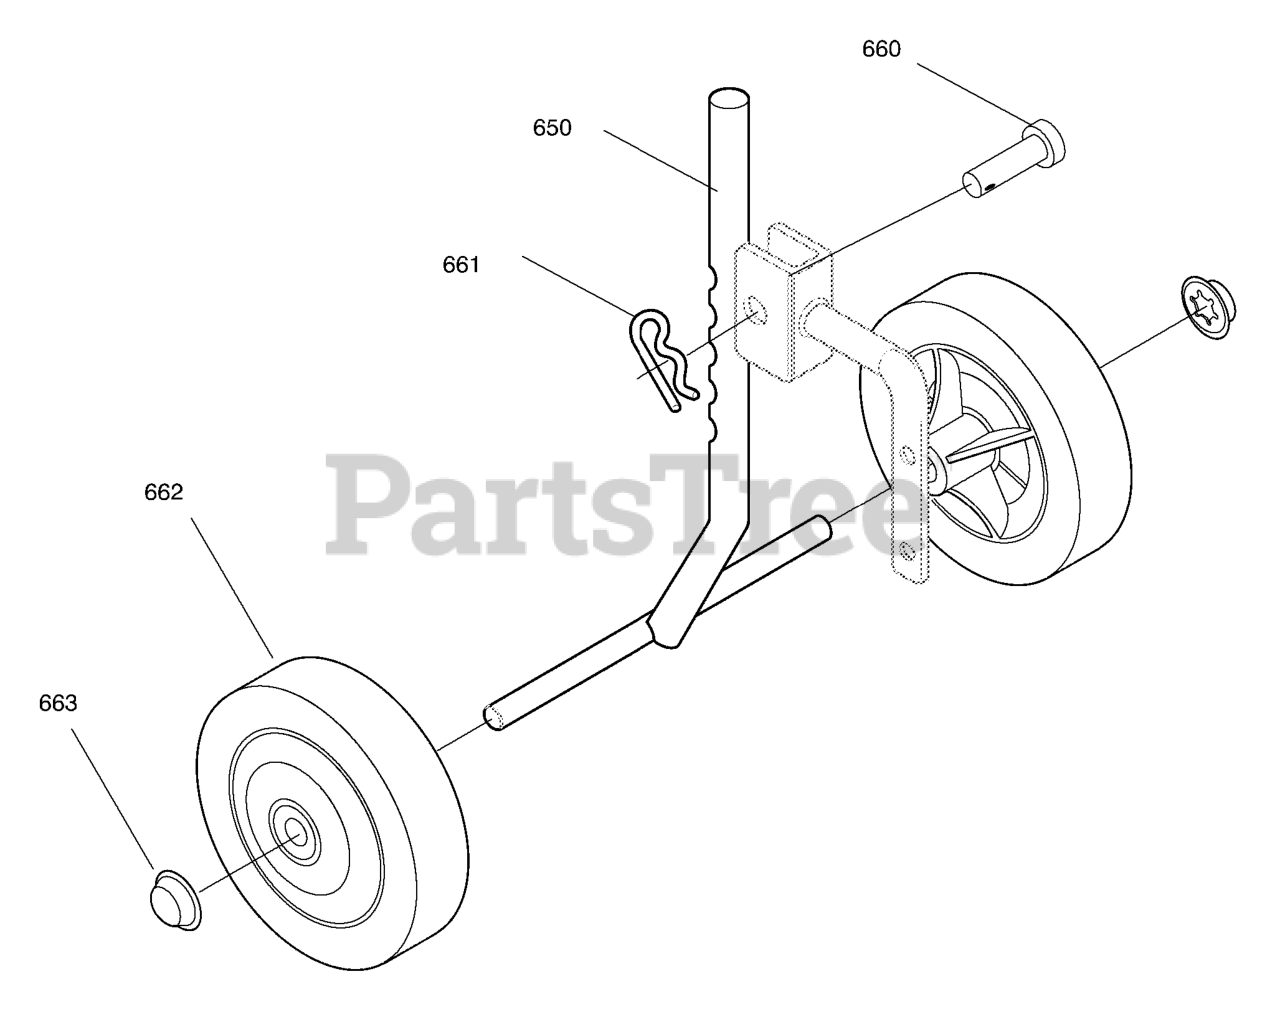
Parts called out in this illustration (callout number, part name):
650	Wheel Support Assy.
660	Clevis Pin
661	Hair Pin
662	Tire & Rim
663	Push On Nut
